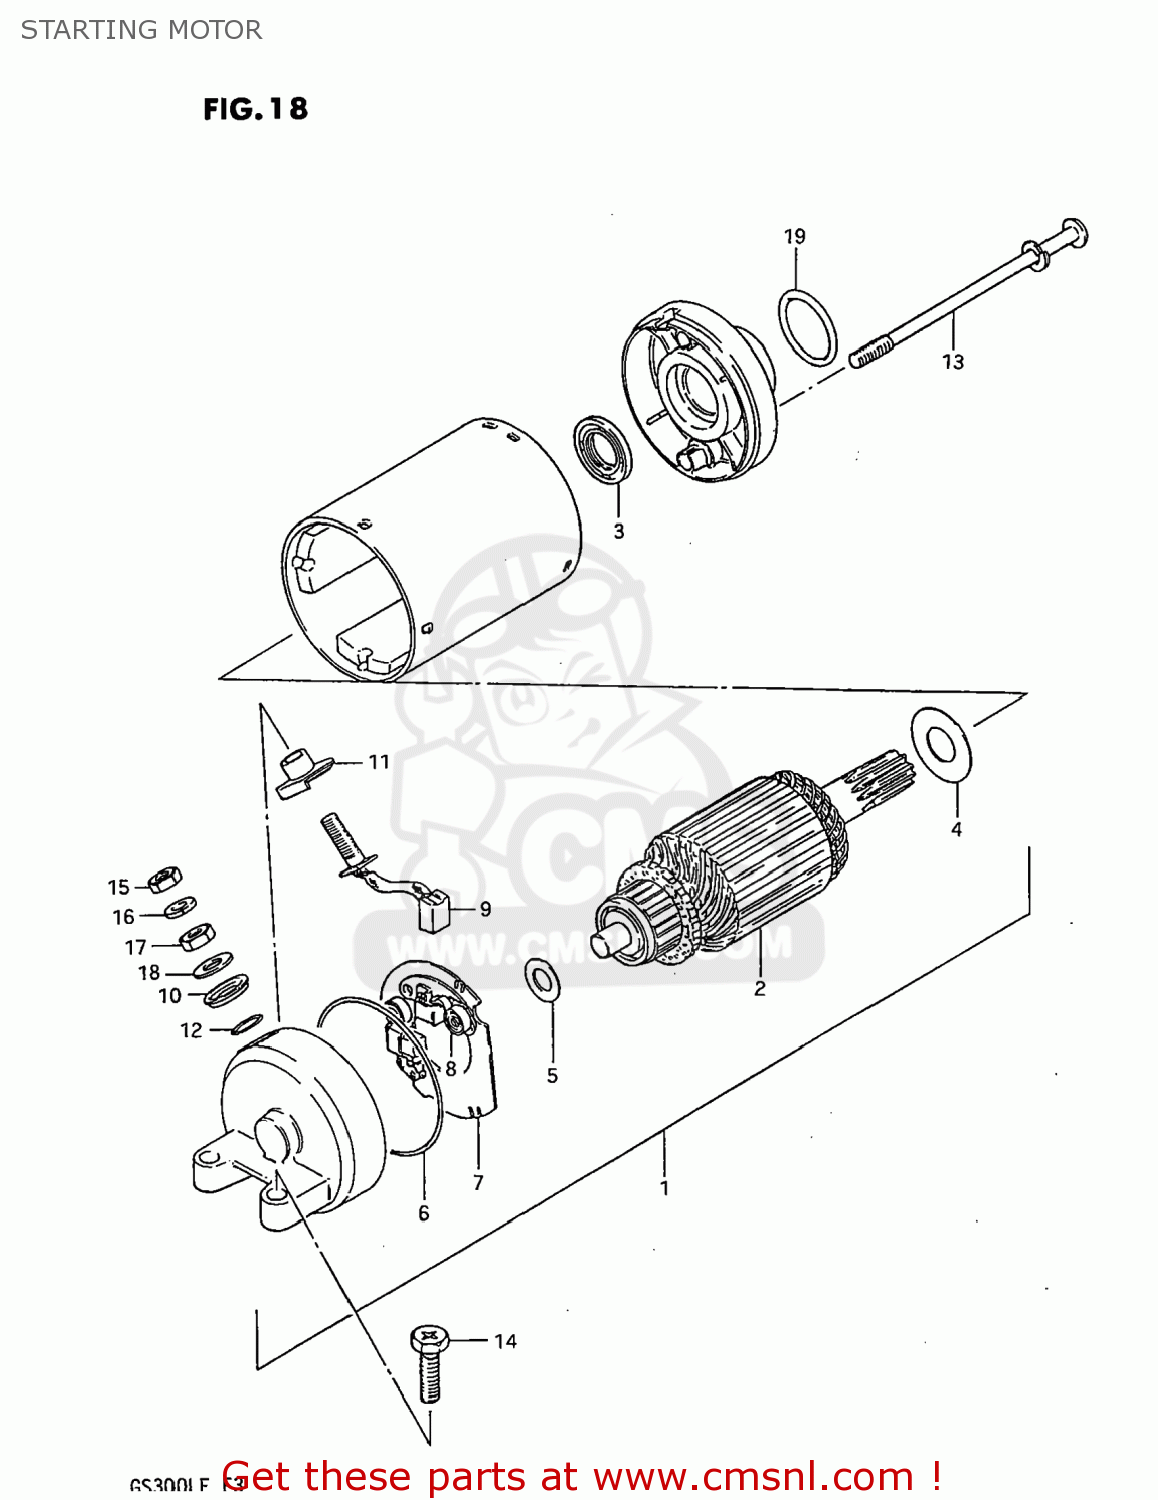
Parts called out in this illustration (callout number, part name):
1	MOTOR ASSEMBLY,STARTING
2	ARMATURE
3	SEAL,OIL
4	RING,SNAP
5	SHIM,ARMATURE
6	O RING
7	HOLDER,BRUSH
8	SPRING
9	BRUSH SUB ASSY,STARTING MOTOR
10	BUSHING (1)
11	BUSH,NO.2
12	O-RING
13	BOLT,STARTING MOTOR HOUSING
14	SCREW (6X25)
15	NUT 6MM
16	LOCK WASHER
17	NUT
18	WASHER,LOCK
19	O RING(D:3,ID:24.5)
